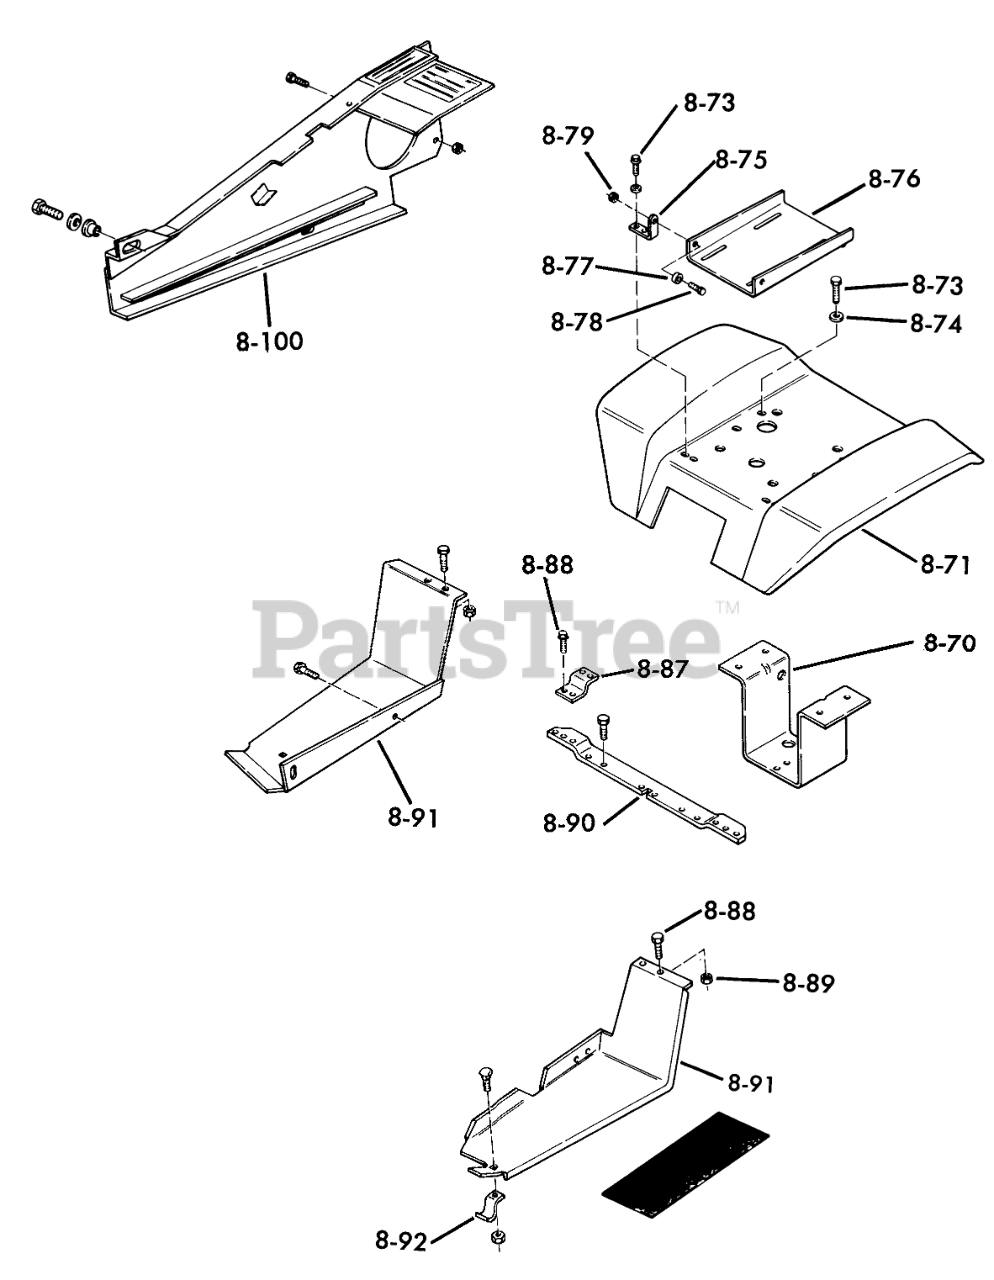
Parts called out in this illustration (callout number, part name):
8-70	Bracket-Fender
8-71	Fender
8-71	Bushing
8-73	Bolt
8-74	WASHER 5/16 SAE
8-75	BRACKET-PIVOT
8-76	Plate Seat Pivot
8-77	BUSHING
8-78	HHCS
8-79	Nut
8-79	BUMPER-RUBBER
8-87	BRACKET-FENDER R
8-88	HHCS
8-88	Nut
8-88	Bracket-Footrest
8-88	SCREW
8-91	Footrest-RH
8-91	Footrest-L.H.
8-91	PAD-FOOTREST
8-91	Bolt
8-91	Nut
8-91	Screw
8-92	BRACKET
8-92	Bolt
8-92	Nut
8-92	Bracket
8-100	Belt Guard
8-100	H H C S
8-100	Screw
8-100	LOCKWASHER
